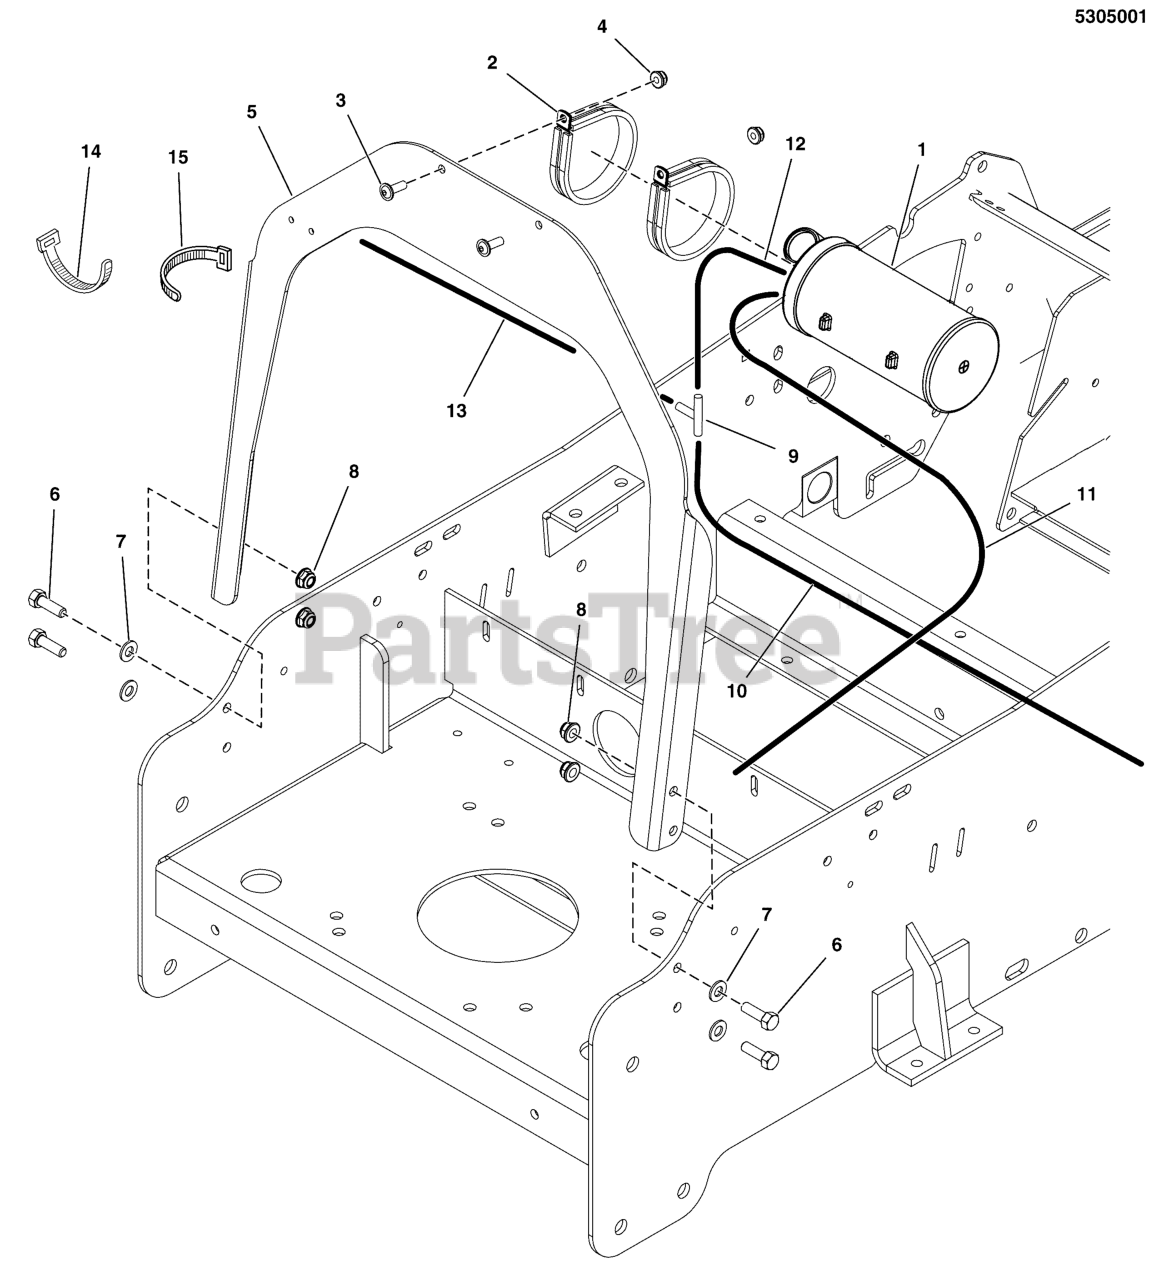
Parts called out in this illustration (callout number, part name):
1	CNSTR, CARB, 9 GAL
2	CLAMP, 3" ID, CUSHIONED, STAINLESS
4	NUT, 1/4-20 Hex Nylock Flange
5	BRACKET, CARB CANISTER, F60Z - BLK
6	BOLT, 5/16-18 X 1" GRD5 YZ
7	WASHER, 5/16" SAE
8	NUT, 5/16-18 HEX NYLOCK FLANGE NUT
9	FITTING, 3/16" TEE, BARB TYPE, HDPE
10	HOSE, VAPOR, 5MM ID, 43.00 LG
11	HOSE, VAPOR, 5MM ID, 36.00 LG
12	HOSE, VAPOR, 5MM ID, 5.50 LG
13	HOSE, VAPOR, 5MM ID, 11.00 LG
14	TIE, SELF-LOCKING, 6"
15	TIE, SELF-LOCKING, 12"
